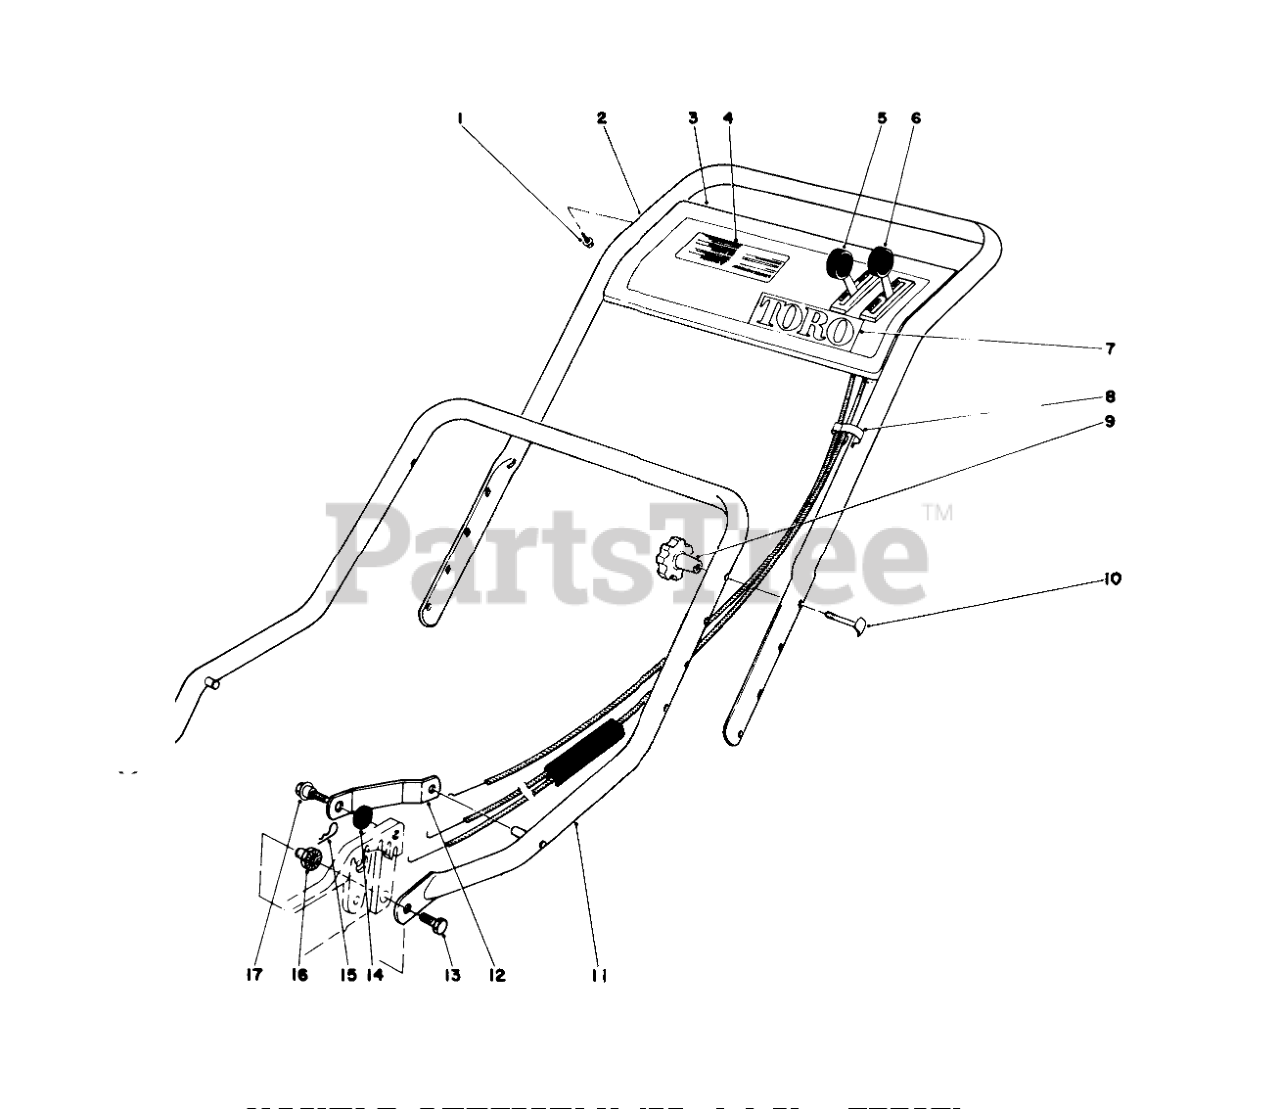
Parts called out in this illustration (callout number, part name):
1	SCREW-HWHTF
2	Upper Handle
3	Control Plate
4	Decal Control Plate
5	Control-Throttle
6	Control-Traction
7	TORO LOGO DECAL
8	BOWDEN CLIP
10	HANDLE SCREW
11	Lower Handle
12	HANDLE LATCH
13	SCREW-HH
14	SPACER
15	PIN-COTTER, HAIR
16	HANDLE PIVOT NUT
17	SCREW-SHOULDER
